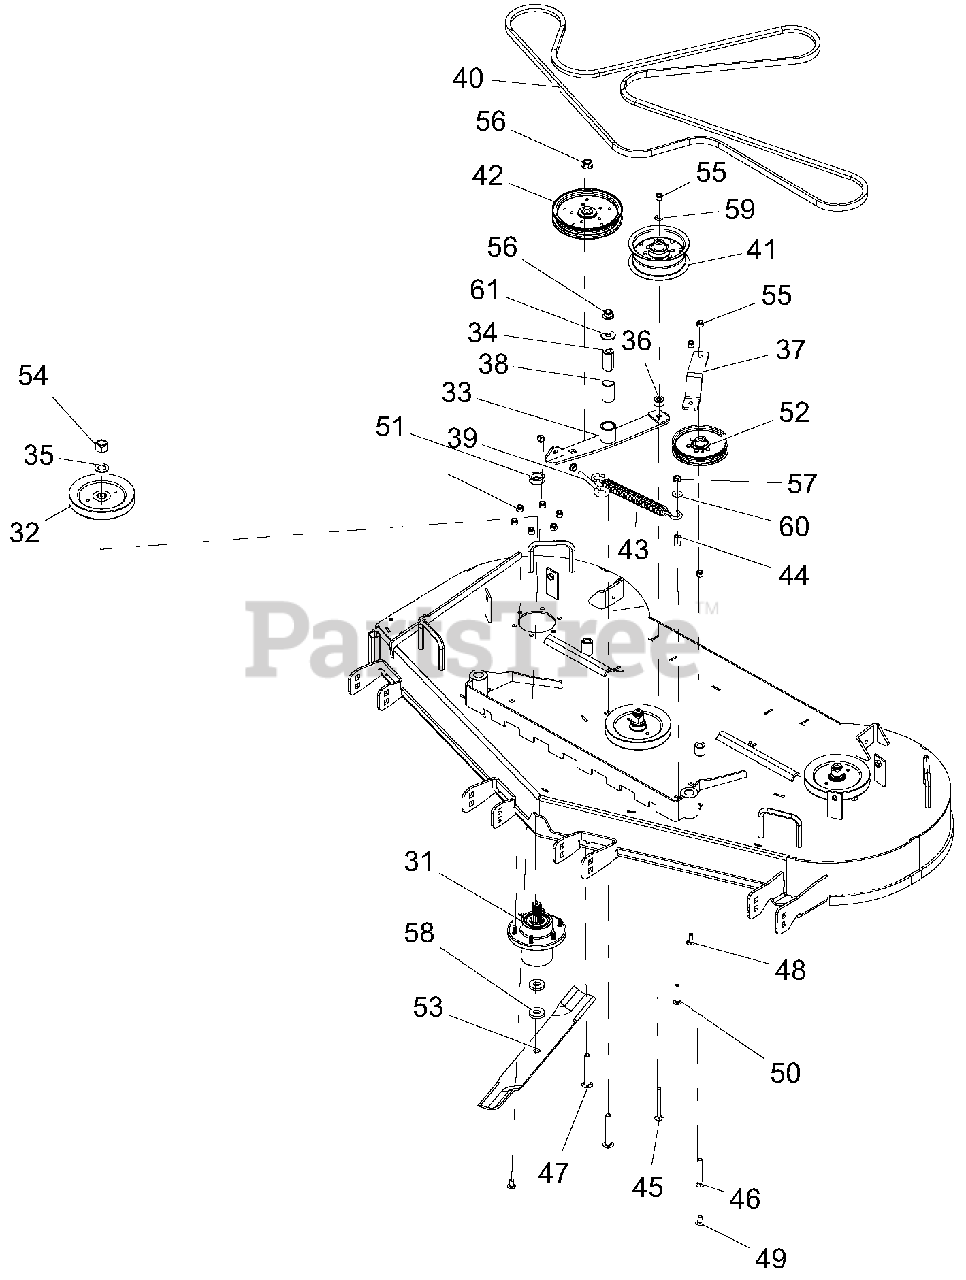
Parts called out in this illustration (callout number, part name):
31	ASSY, SPINDLE HOUSING
32	PULLEY, SPINDLE 6.34 OD
33	WLDMT, IDLER 61 WALK
34	BSHG, SPCR .502X.997X2.03
35	WASHER, .75X1.3125X.120
36	SPACER, .437X1.00X.58 SMLS
37	STRAP, IDLER 48/52 WALK
38	BSHG, 1.00X1.125X1.937
39	BOLT, EYE .38-16X4.50 .75 DIA
40	BELT, 61" FLWLK
41	PULLEY, FLAT 5.00X2.36X.375
42	IDLER-FLAT-PLY 6.75X.510
43	SPRG, EXTENSION
44	BUSH.,S.391X.622X.95 ST REV A
45	@BLT-RDHDSQNK .38-16X3.50 G5 YWZC
46	@BLT-RDHDSQNK .38-16X3.00 G5 YWZC
47	@BLT-RHDSSQNK .50-13X3.50 G5YZ
48	@BLT-RDHDSHSQNK.38-16X1.0 G5YZ
49	@BLT-RHDSSQNK .38-16X.75 G5YZ
50	@BLT-RHDSSQNK .38-16X2.00 G5YZ
51	SPACER, 1.500X1.000X.510 Y
52	PULLEY, FLAT 5.00X.375 W/BRG
53	BLADE, 21.000 X .80 LIFT
54	LOCKNUT, 3/4-16 CROWN GR5 Y
55	@NUT-LK-NYL .38-16 YWZC
56	NUT-LK-NYL-FLG .50-13 YWZC
57	@NUT-SPNLK-FLG .375-16 YWZC
58	WSHR-FL-STL .630X1.50X.25 YWZC
59	@WSHR-FL-STL.406X.812X.065 YWZ
60	@WSHR-FL-STL.438X1.00X.083 YWZC
61	@WSHR-FL-STL.563X1.38X.109YWZC
